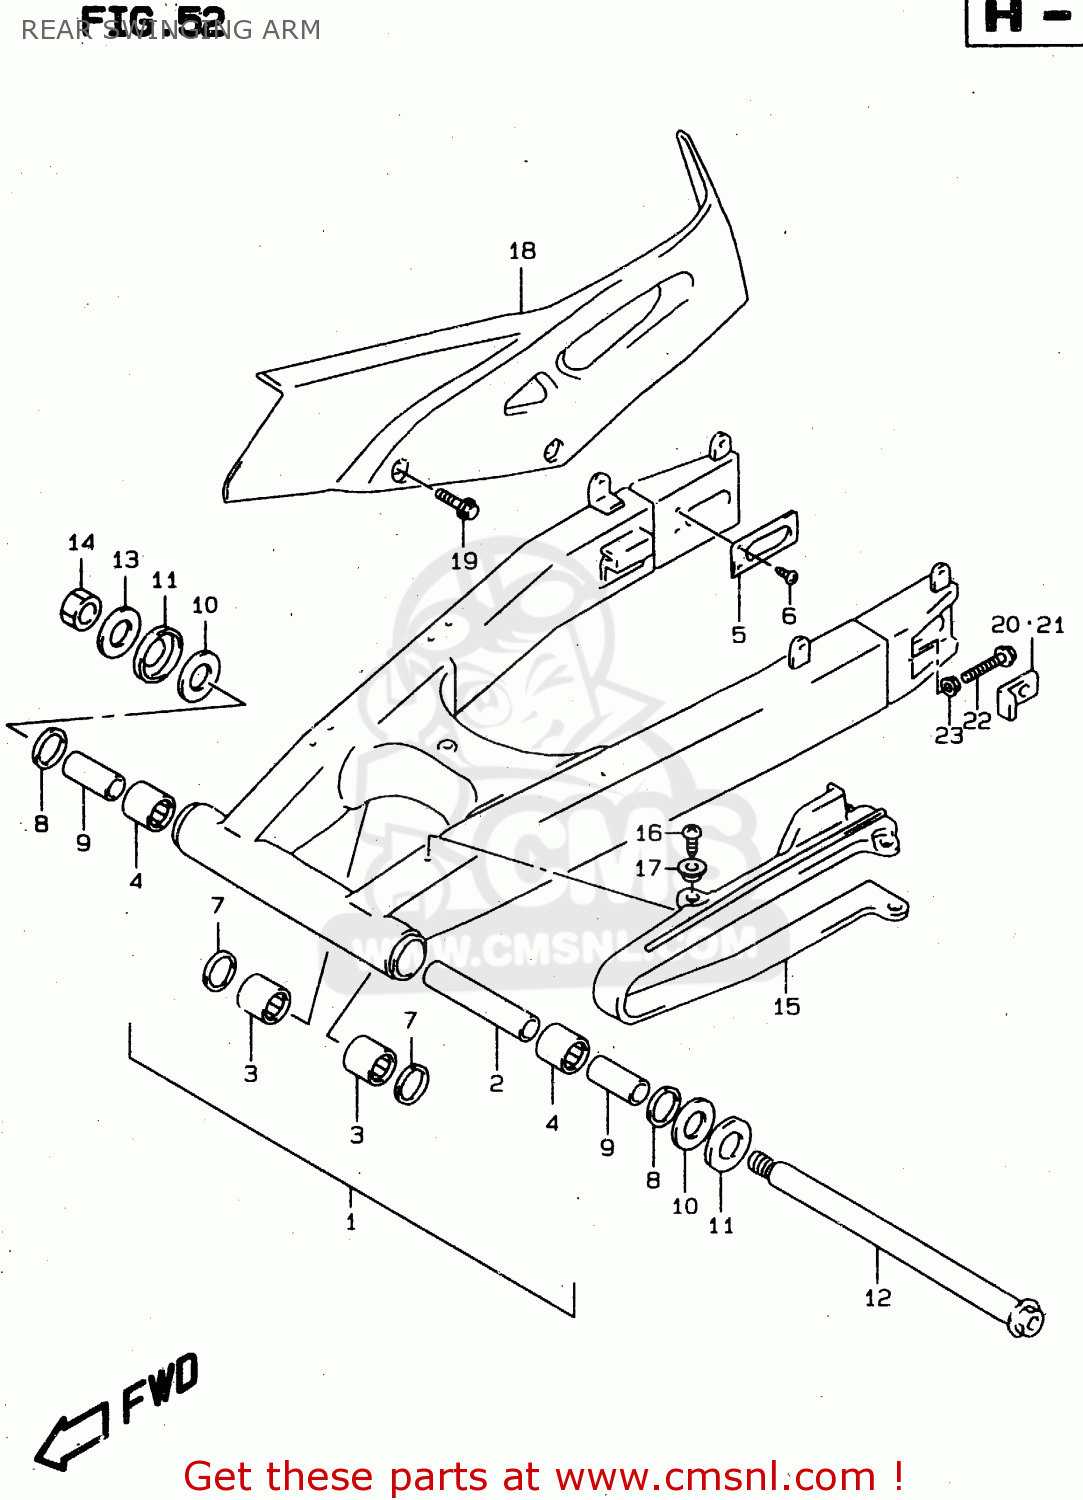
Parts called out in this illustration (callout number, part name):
1	SWINGINGARM ASSY,RR
2	SPACER,SWGARM PIVOT CTR
3	BEARING(20X27X23.5)
4	BEARING(22X29X30)
5	PLATE,RR SWING ARM BRKT
6	SCREW 6X10
7	SEAL,OIL(20X27X5)
8	SEAL,OIL(22X29X4)
9	SPACER,SWGARM PIVOT BRG
10	WASHER
11	COVER,SWINGINGARM PIVOT
12	AXLE,RR
13	WASHER, FIXED DRIVE FACE
14	NUT
15	BUFFER,CHAIN TOUCH DEFENSE
16	SCREW 6X12
17	WASHER
18	CASE,CHAIN
19	BOLT,CHAIN CASE
20	WASHER,CHAIN ADJUSTER
21	WASHER,CHAIN ADJUSTER
22	BOLT(8X50)
23	NUT
